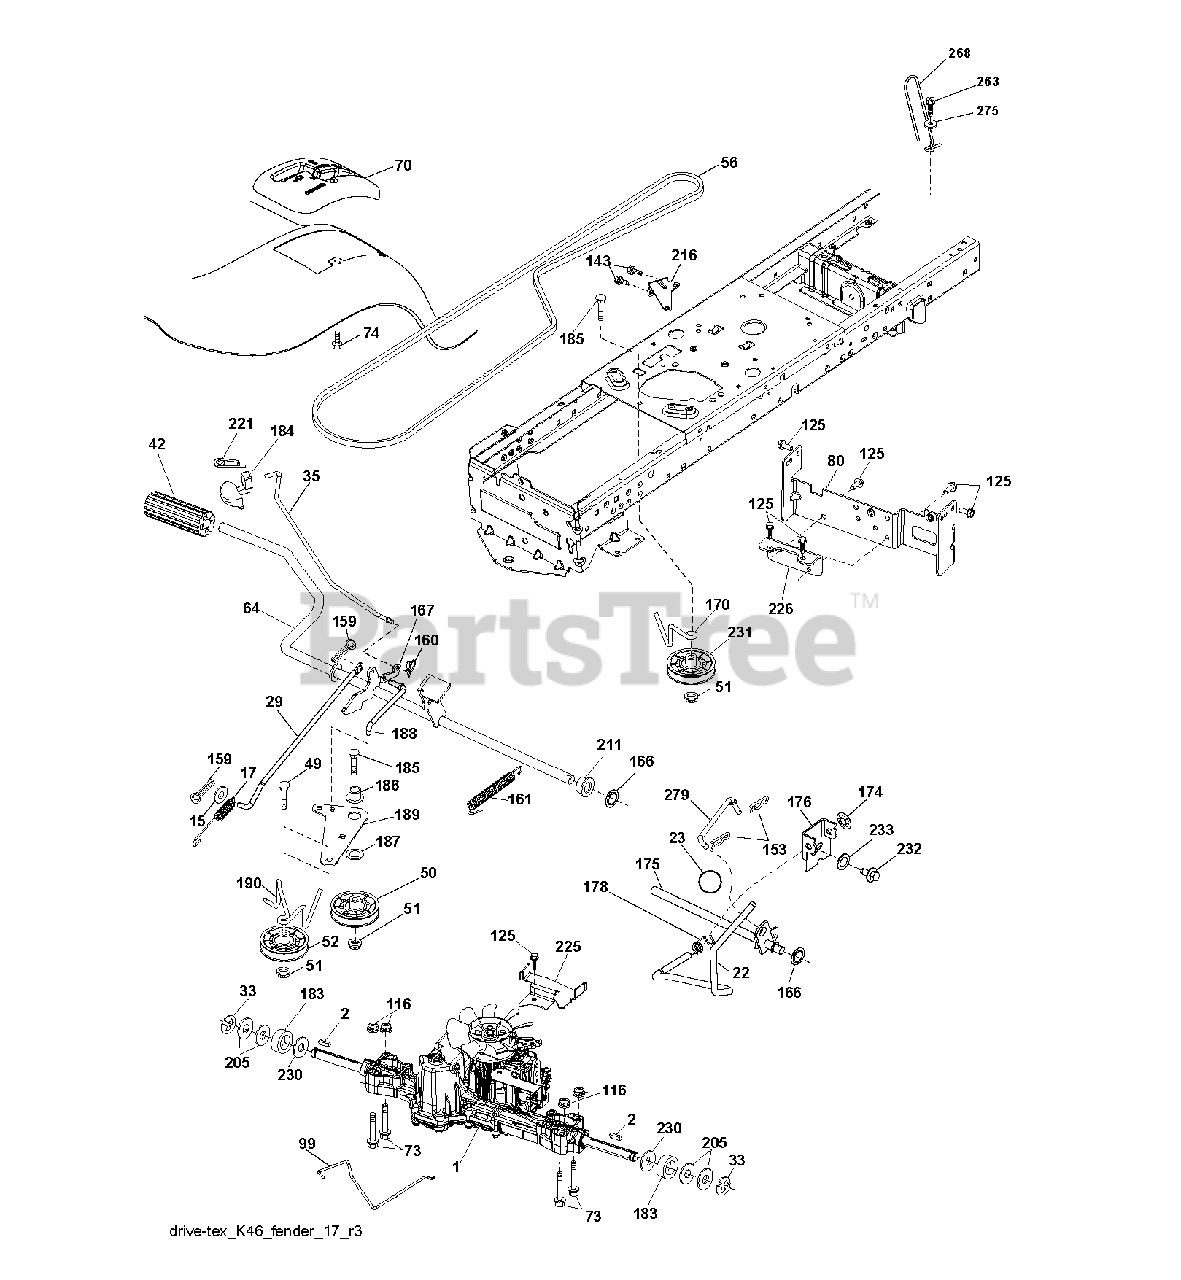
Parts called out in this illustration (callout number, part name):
2	SQUARE KEY
17	SPRING.BRAKE.K46.GREEN
22	ROD.SHIFT.FENDER.TLT.2006
23	KNOB.DUCKHEAD.1/2
29	ROD.BRAKE.K46
33	E-RING LT
35	ROD, BRAKE, PARK
42	PEDAL COVER T
49	BOLT
50	IDLER.FLAT.910.OFFSET
51	NUT LOCK FLG 3/8-16 UNC
52	IDLER.V-GROOVE.910.OFFSET
64	SHAFT.ASM.PEDAL.BRAKE.
70	CONSOLE.SHIFT.STL.HYD.BLACK
73	BOLT HEX 5/16-18 GR 5
74	SCREW.HI-LO.CONSOLE
80	STRAP TORQUE
99	ROD.SPRING.BYPASS.K46.LT.Z
116	NUT LOCK HEX FLANGE 5/16-18
125	SCREW
153	RETAINER M
159	COTTER PIN
160	RETAINER CLIP
161	SPRING, RETURN LT
166	NUT.PUSH.625
167	LATCH.BRAKE.SPRING
170	KEEPER.CENTER SPAN.1.688
174	NUT.PUSH.500.2006
175	SHAFT.ASM.SHFT.T2.TLT
176	ARM.CLEVIS.ROD.SHIFT
178	SPRING.SHIFT.GT2006
183	SPACER AXLE
184	HANDLE PARKING BRAKE
186	SPACER.RETAINER
187	WASHER 12/32X2X10GA
188	LINK.CLUTCH.GROUND.DRIVE
189	BELLCRANK.GROUND.DRIVE.TEX.
190	KEEPER.BELLCRANK.DRIVE
211	BUSHING.SHAFT.BRAKE.HAND
216	BRACKET.PULLEY.IDLER.W/TEX
221	RETAINER.SPRING.CLIP.H
225	KEEPER.BELT.TRANSAXLE.K46
226	BRACKET.MOUNT.TORQUE.K46.TLT
230	WASHER.HARDENED
231	IDLER.V-GROOVE.1.688.OFFSET
232	BOLT FIN HEX 7/16-14 X 1
233	WASHER SERRATED
263	SCREW, 3/8-16X3/4
275	WASHER
279	LINK.SHIFT.
